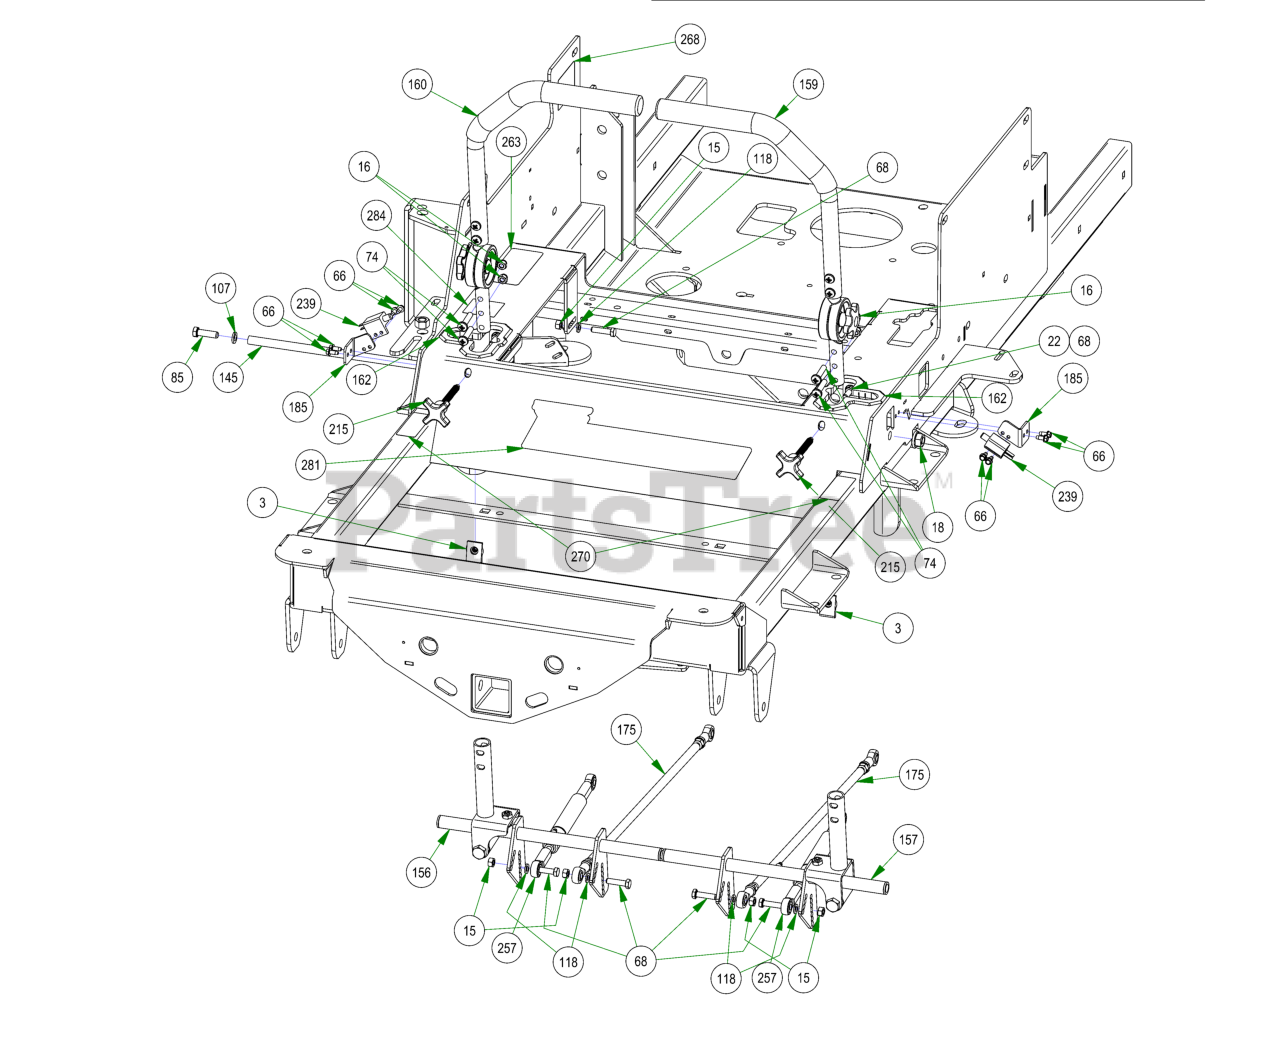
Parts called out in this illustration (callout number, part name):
3	Extruded Nut 3/8"-16 3/4" Hole Center With Patch
11	3/8-16 HEX NUT ZINC
15	5/16-18 HEX NUT ZINC
16	5/16-18 NYL INS L/N ZC
18	1/2-13 NYLON INSERT FLANGE LOCKNUT ZINC
22	5/16-18 HEX SERRATED FLANGE NUT HARD/ZINC
62	5/16-18 x 5/8 Hex Bolt
66	12-24 X 1/2 HEX WASHER UNLSOT F TCS ZINC
68	5/16-18 X 1-1/4 HEX C/S (GR.5) ZC
74	5/16-18 x 1 3/8" Futton Head Torx Drive Bolt
85	3/8-16 X 1-1/4 HEX CAP SCREW (GR.5) ZINC
91	3/8-16 X 1-1/2 HEX CAP SCREW (GR.5) ZINC
107	3/8 SPLIT LOCKWASHER ZINC
115	1/4 USS FLAT WASHER (3/4 OD) ZINC
117	5/16 USS FLAT WASHER (7/8 OD) ZINC
118	5/16 SPLIT LOCKWASHER ZINC
145	2019 Steering Actuator Rod
156	2019 R Series RH Arm Rod Assembly
157	2019 R Series LH Arm Rod Assembly
159	2019 Left Hand ADJ. Steering Arm Kit
160	2019 Right Hand ADJ. Steering Arm Kit
162	Snap-in Drive Arm Bushing
175	2019 Outlaw Gen2 XP Push Rod Assembly
185	2019 Arm Switch Bracket
215	Speed Limiting Knob 3/8-16X 3"
224	2021 LH ROGUE HYDRO TANK LINE ASSY
225	2021 RH ROGUE HYDRO TANK LINE ASSY
235	2023 Rogue Frame - Painted
239	Safety Switch
257	2019 SROID Damper With Spherical Rod Ends
263	2023 EPA Build Date Punch Decal
268	Hydraulic Decal
270	2018 LH/RH Steering Control Decal Roll
281	2019 Rogue Cooler Cover Decal
284	2019 Deck Release Decal
